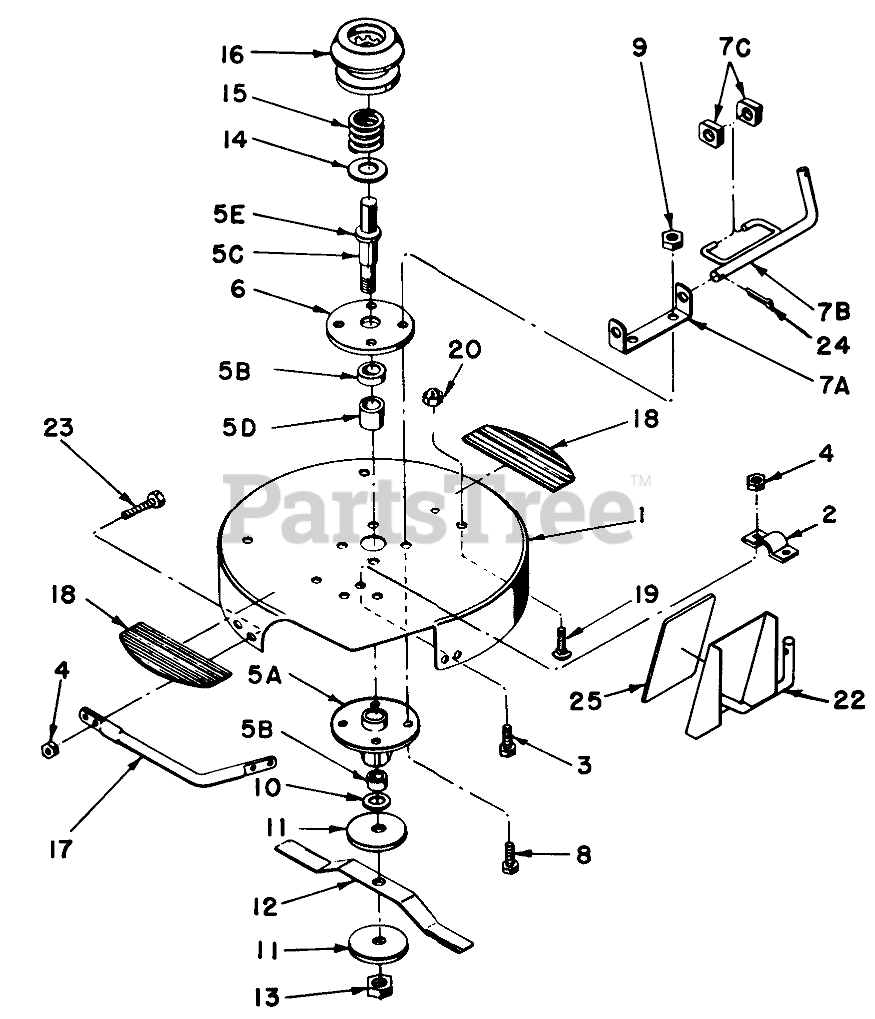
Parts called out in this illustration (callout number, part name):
1	Mower Housing
2	Bracket, Clutch
3	SCREW-HH
5	Blade Spindle and Housing Assy
5A	a.Spindle Housing
5B	Bearing
5C	c.Spindle
5D	d.Spacer, Spindle
5E	Bearing Washer
6	Washer
7	Blade Control Bracket Assy
7A	a.Bracket, Blade Control
7B	b.Blade Throwout Assy
7C	c.Brake Shoe
8	SCREW-HH
9	Nut
10	WASHER
11	WASHER
12	Blade
14	Washer, Thrust
15	Spring, Blade Clutch
16	Clutch Disc. Assy
17	Blade Guard
18	Footpad
19	Screw
20	7/8X046 IN SNAP RING
21	WASHER-LOCK
22	Clutch Pedal Assy
23	SCREW-CARR
24	PIN-COTTER
25	Foot Pad
